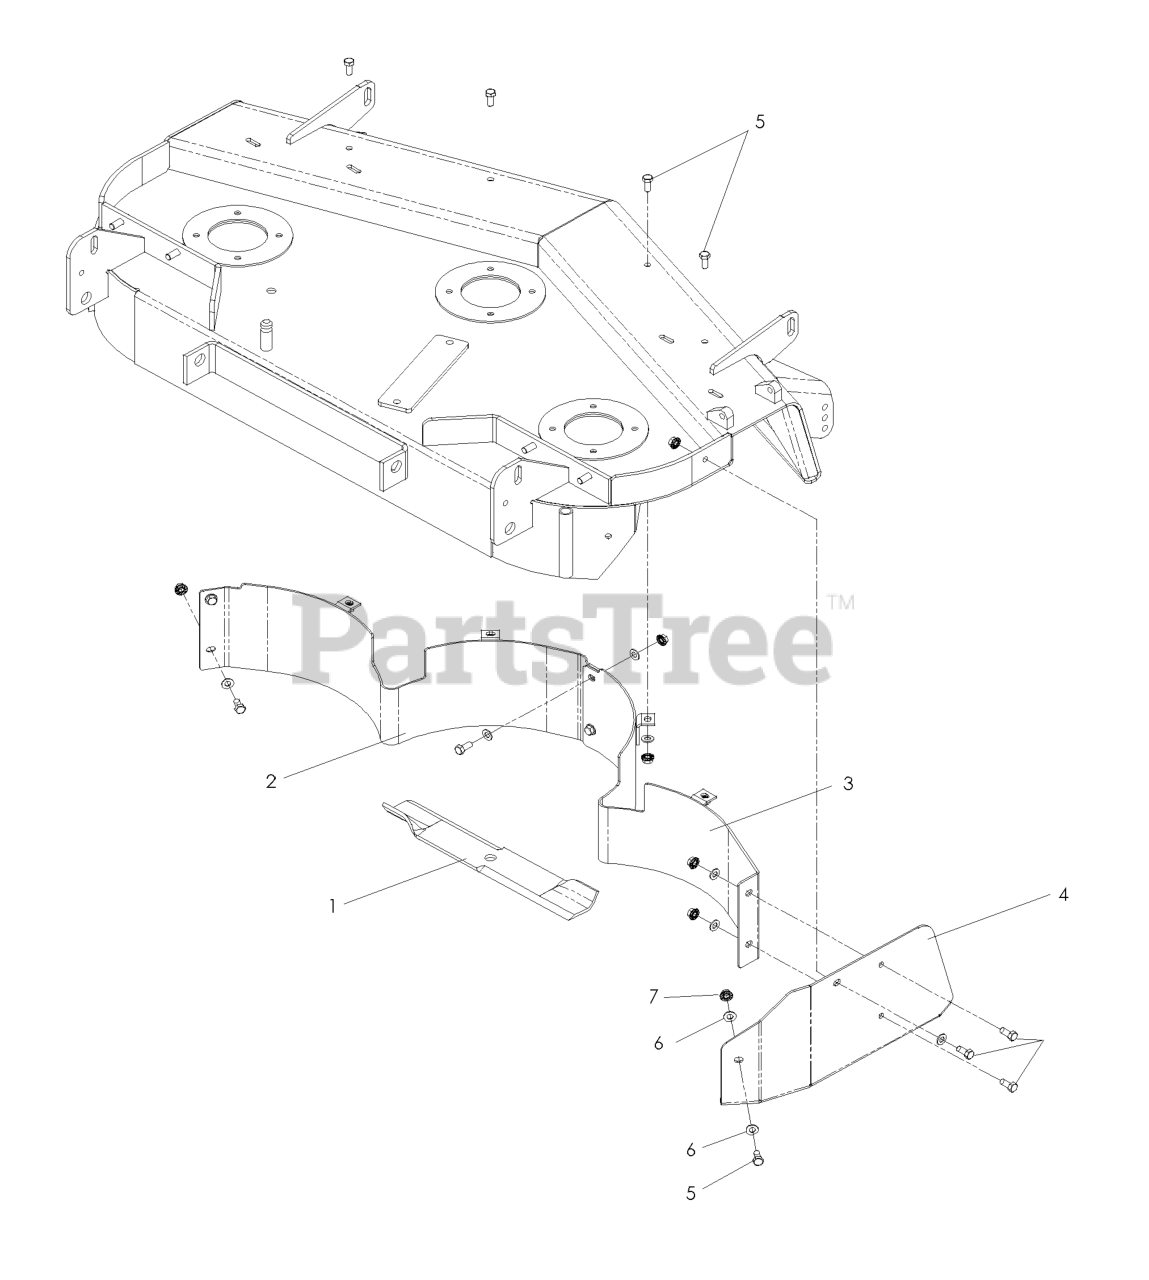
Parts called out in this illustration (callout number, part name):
1	BLADE MULCH 14-7/8"
1	BLADE MULCH 16-1/4"
1	BLADE MULCH 18"
1	BLADE MULCH 21"
2	MULCH BAFFLE, LEFT, 42
2	BAFFLE WLDMT 42" LH
2	BAFFLE WLDMT, 52" L.H.
2	BAFFLE WLDMT, 61" L.H. MULCH
3	BAFFLE WLDMT, 42" R.H. MULCH
3	BAFFLE WLDMT 48 RH
3	BAFFLE WLDMT, 52" R.H. MULCH
3	BAFFLE WLDMT 61" R.H. MULCH
4	MULCH CAP 42"
4	MULCH CAP 48
4	MULCH CAP 52
4	MULCH CAP 61
5	HCS 5/16C X 3/4
6	FLAT WASHER 5/16 SAE
7	NUT 5/16C WHIZ
